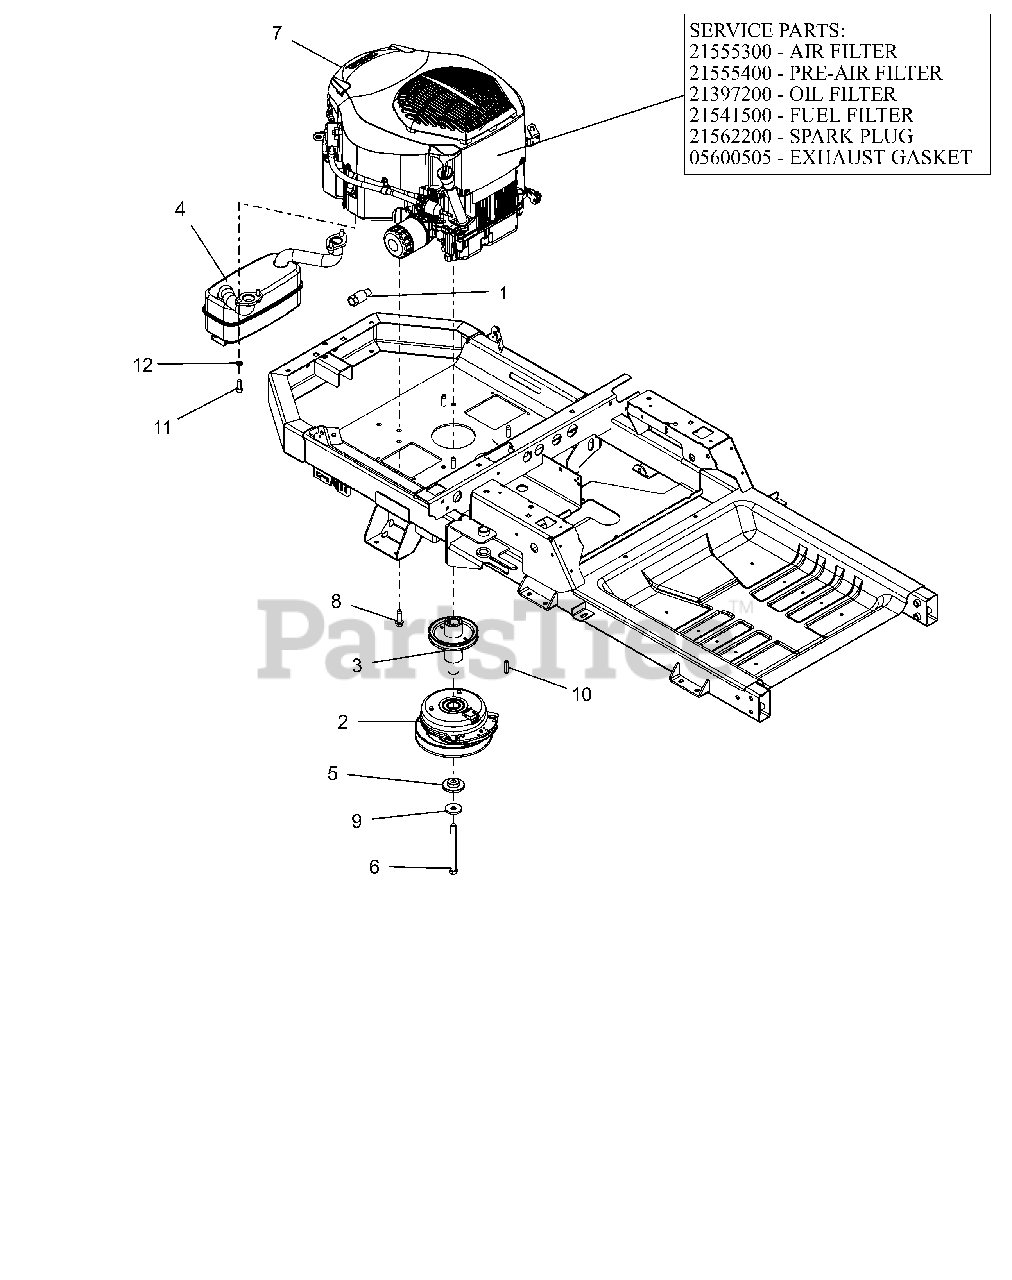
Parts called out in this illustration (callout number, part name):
1	DRAIN, OIL
2	CLUTCH,105FTLB MONOPOLE 6.83"
3	WLDMT, DRIVE SHEAVE (LG XL)CZC
4	MUFFLER - KOHLER
5	BSHG-FLG .469X1.06X.574X2.0
6	BLT-HEX.438-20X5 GR8 YZ NYTORQ
7	ENGINE, KOHLER 26 HP PRO W/SC
7	AIR FILTER, KOHLER
7	PRE CLEANER, KOHLER
7	FILTER, OIL - KOH CV20
7	FILTER, FUEL
7	PLUG, SPARK (RFI)
7	GASKET, MUFFLER KOHLER TWIN
8	SCR,TAP .375-16X1.25HWH TR ZCC
9	WASHER, 7/16" SPRING DISK
10	KEY-SQ .25 X 1.25 X .25 SAE
11	SCR, SKH .312-18X.875 GR8 ZCC
12	WSHR,LK-REG .312X.078 ZCC
